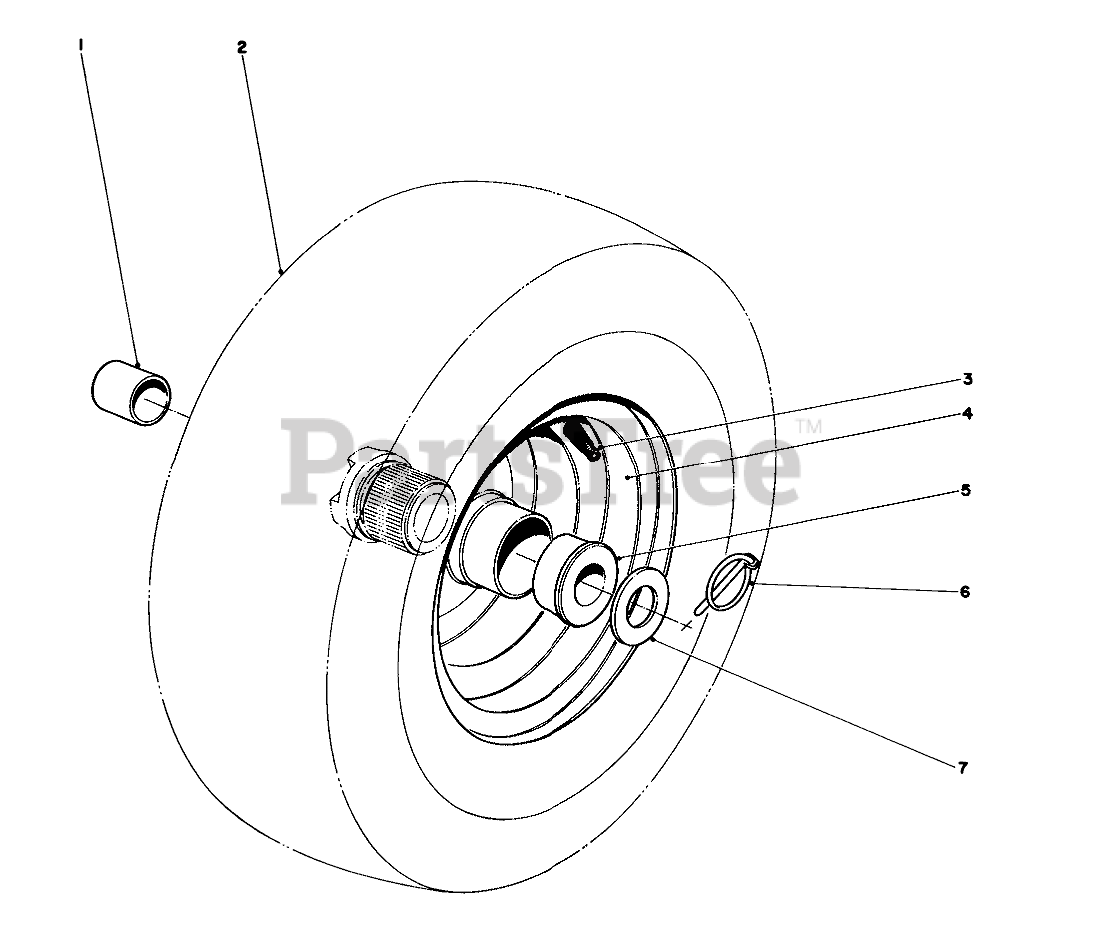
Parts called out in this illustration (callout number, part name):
1	.877ID X .750LG BSHG
2	Tire
3	STEM-VALVE
4	Wheel Rim
5	Bushing
6	PIN-LYNCH
7	WASHER-THRUST
